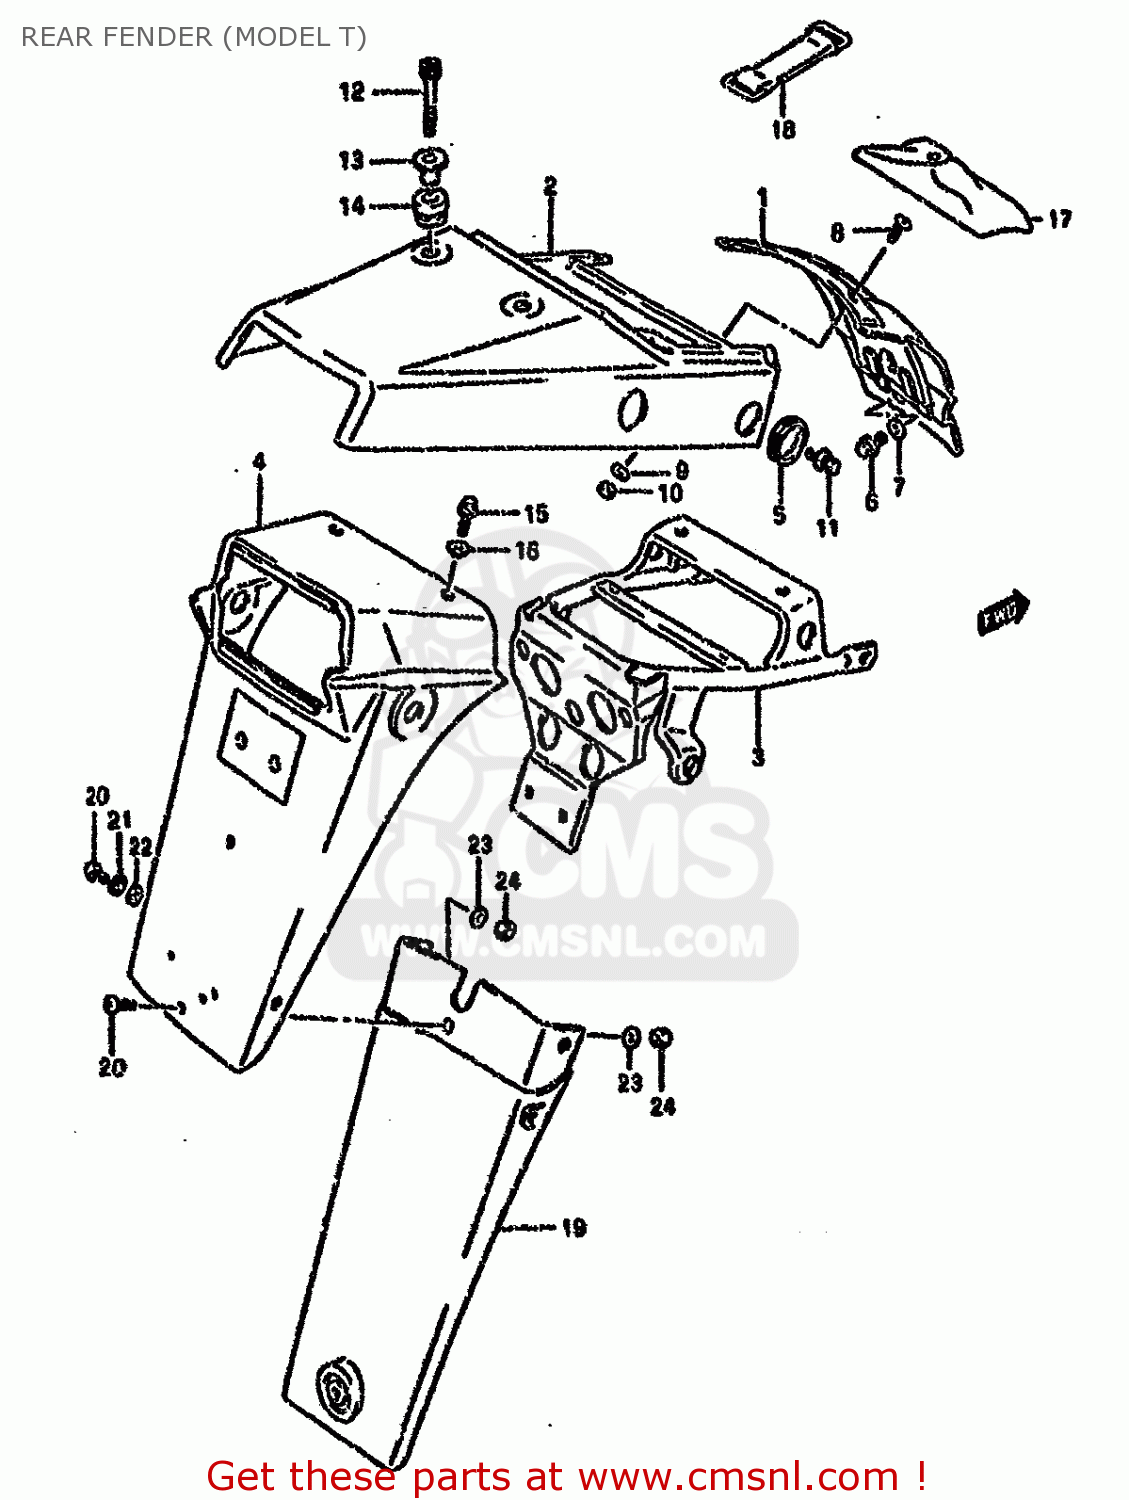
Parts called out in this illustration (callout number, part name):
1	BODY,REAR FENDER FRONT
2	BODY,RR FENDER RR
3	REINFORCEMENT,FENDER
4	EXTENSION,RR FENDER
5	GROMMET
6	BOLT
7	WASHER
8	SCREW (M5X16)
9	WASHER(5.5X16X1.2)
10	NUT 8MM
11	BOLT
12	BOLT
13	SPACER(8.6X12X18.5)
14	CUSHION
15	BOLT
16	WASHER
17	TOOL ASSY
18	MUDGUARD,RR FENDER
19	MUDGUARD,RR FENDER
20	SCREW
21	WASHER
22	WASHER
23	NUT
24	NUT
